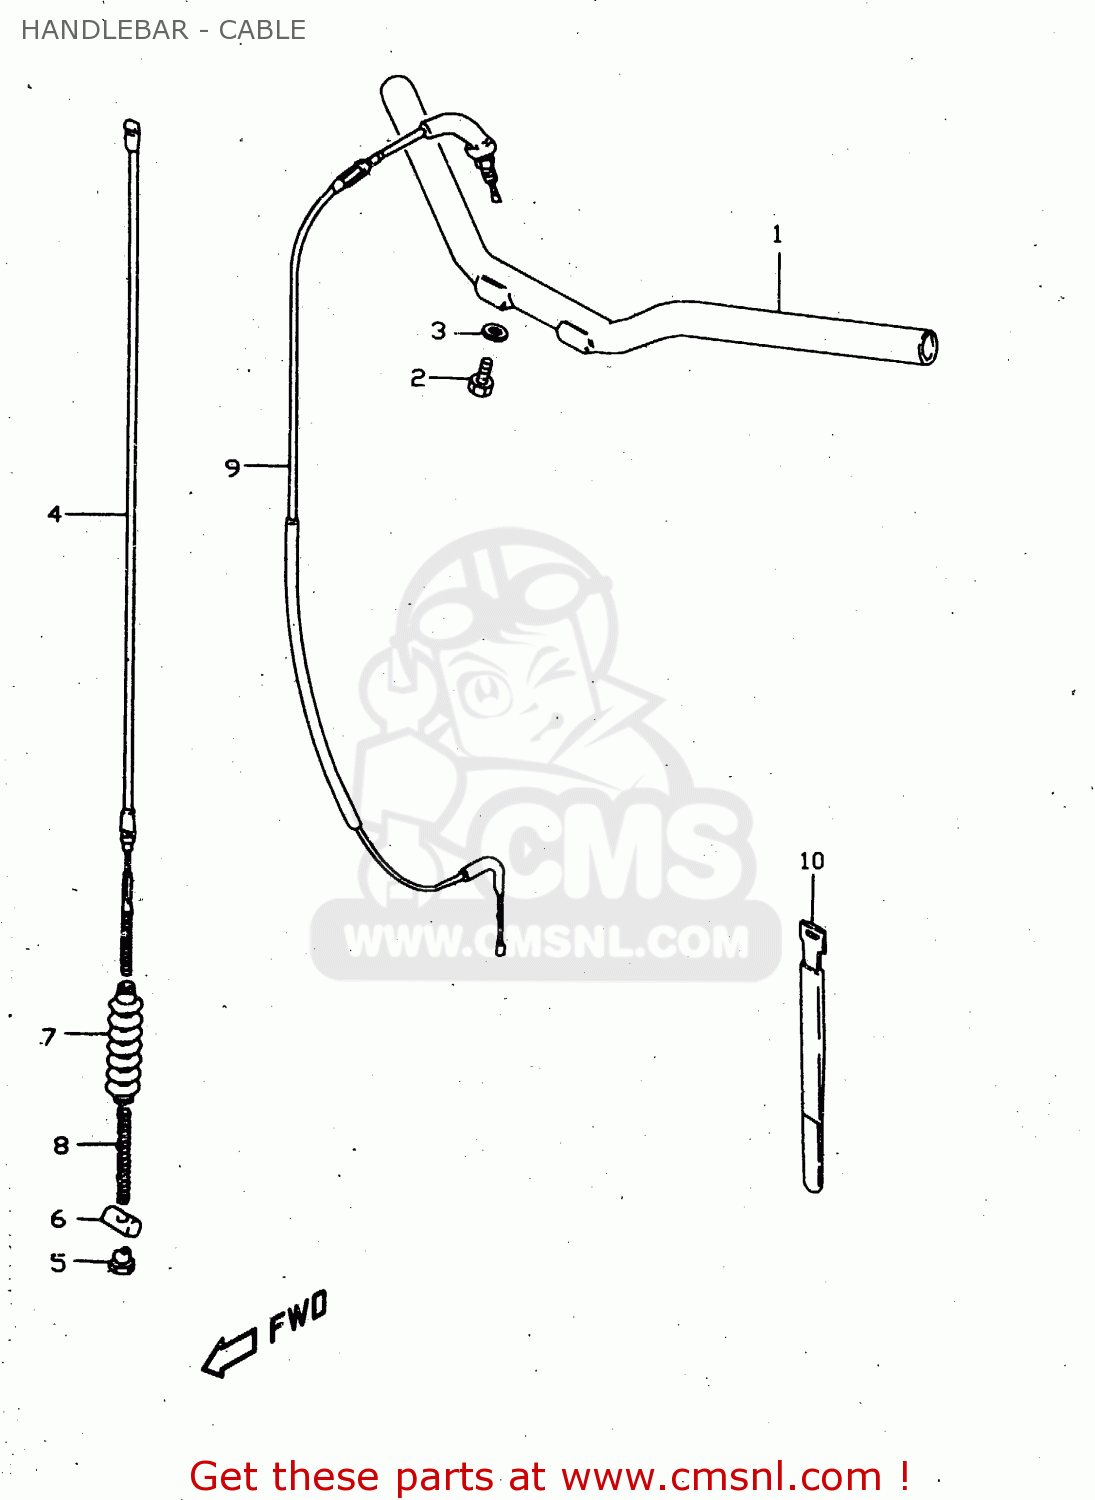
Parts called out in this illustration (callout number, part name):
1	HANDLEBAR
2	BOLT
3	LOCK WASHER
4	CABLE ASSEMBLY,FRONT BRAKE
5	NUT
6	PIN,10X19
7	SEAL,DUST(7X16X75)
8	SPRING
9	CABLE ASSEMBLY,THROTTLE
10	CLAMP(L:235)
